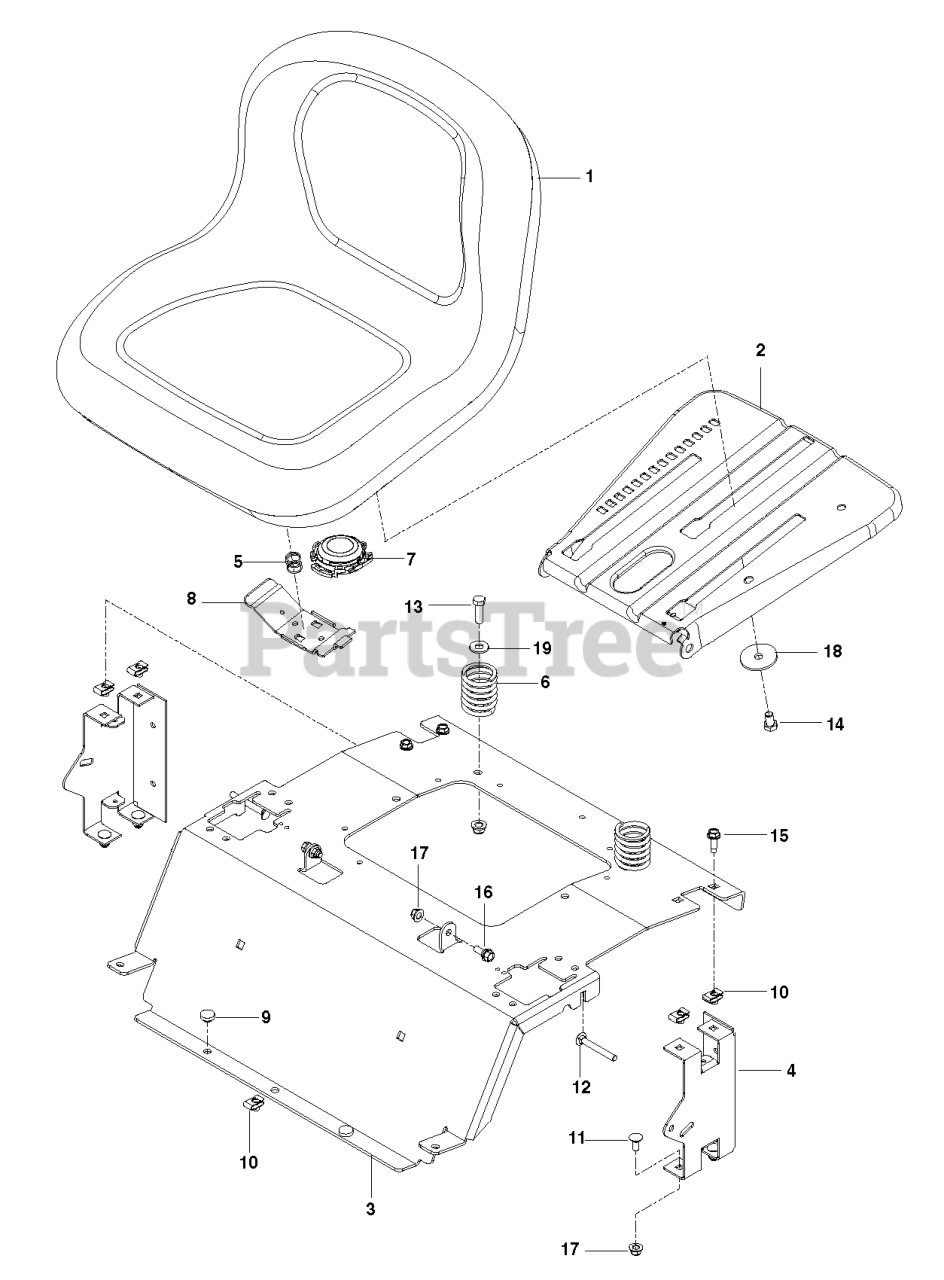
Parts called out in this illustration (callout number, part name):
1	SEAT.TG150.BLK.NLOGO.
2	PAN.ASM.SEAT.3PT
3	SUPPORT.SEAT.PNT.MS428
4	SUPPORT REAR SEAT BLACK
5	SPRING.LATCH.SEAT.TEX
6	Spring Seat Cprsn 2 250 Blk Zi (AYP part number)
7	SWITCH, SEAT N/C
8	HANDLE.SLIDE.SEAT.TEX.BLACK
9	GROMMET, BUMPER
10	U-CLIP 5/16-18 NUT RETAINER
11	Bolt, Carriage 5/16-18 x 3/4 Gr. 5
12	RHSNB 5/16-18 X 2-1/2 GR5 ZD
13	Bolt Fin Hex 3/8 - 16 UNC x 1-1/4 (AYP part number)
14	HCS 3/8-16 X 5/8 GR 5 ZD
15	BOLT 5/16-18 X 3/4
16	BOLT, SHOULDER
17	5/16-18 NYLOC FLANGE NUT
18	WASHER, 3/8 SPEC
19	WASHER 3/8 FLAT
